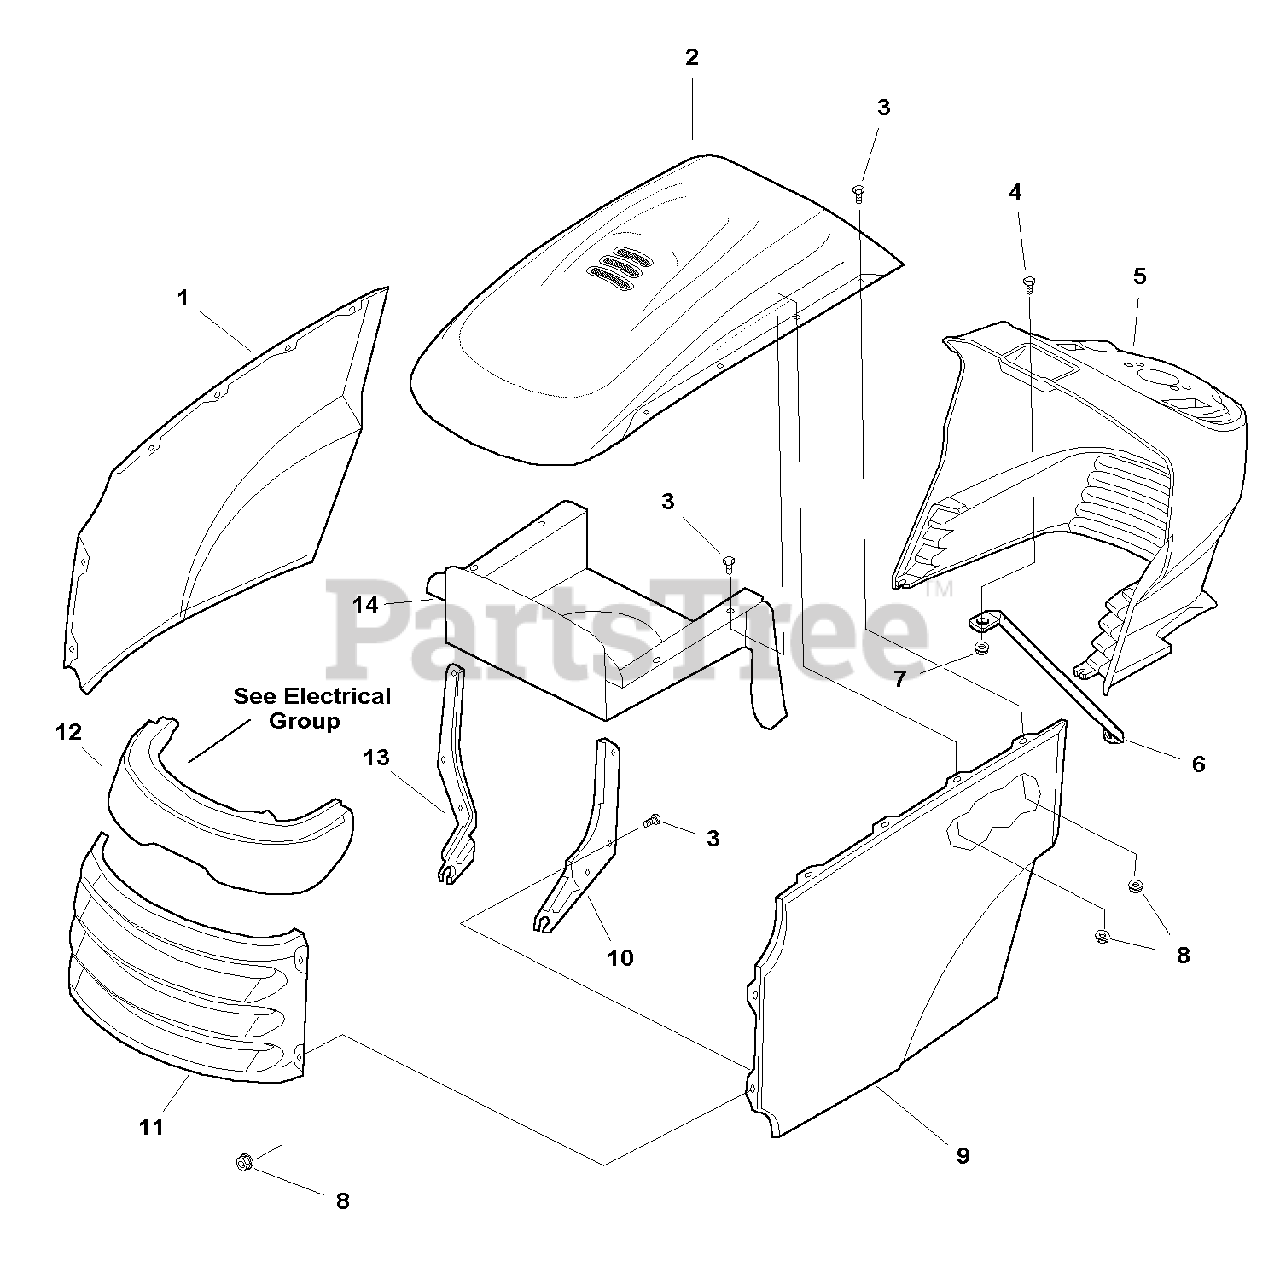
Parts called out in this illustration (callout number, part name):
1	PANEL, RH Side, Orange
1	PANEL, RH Side, Red
2	HOOD, w/Louver, Orange
2	HOOD, w/Louver, Red
3	CAPSCREW, Hex Flange Whiz Lock, 1/4-20 x 5/8
4	SCREW, Pan Head Phillips, #10-24 x 1
6	ROD, Dash Support
7	NUT, Hex Lock, w/Nylon Insert, 10-24
8	NUT, Hex Flange Whiz Lock, 1/4-20, Large, Black
9	PANEL, LH Side, Orange
9	PANEL, LH Side, Red
11	GRILLE, Orange
11	GRILLE, Red
12	HEADLIGHT ASSEMBLY, 4 Bulb (See Electrical Group for internal components)
14	DUCT, Air Inlet
